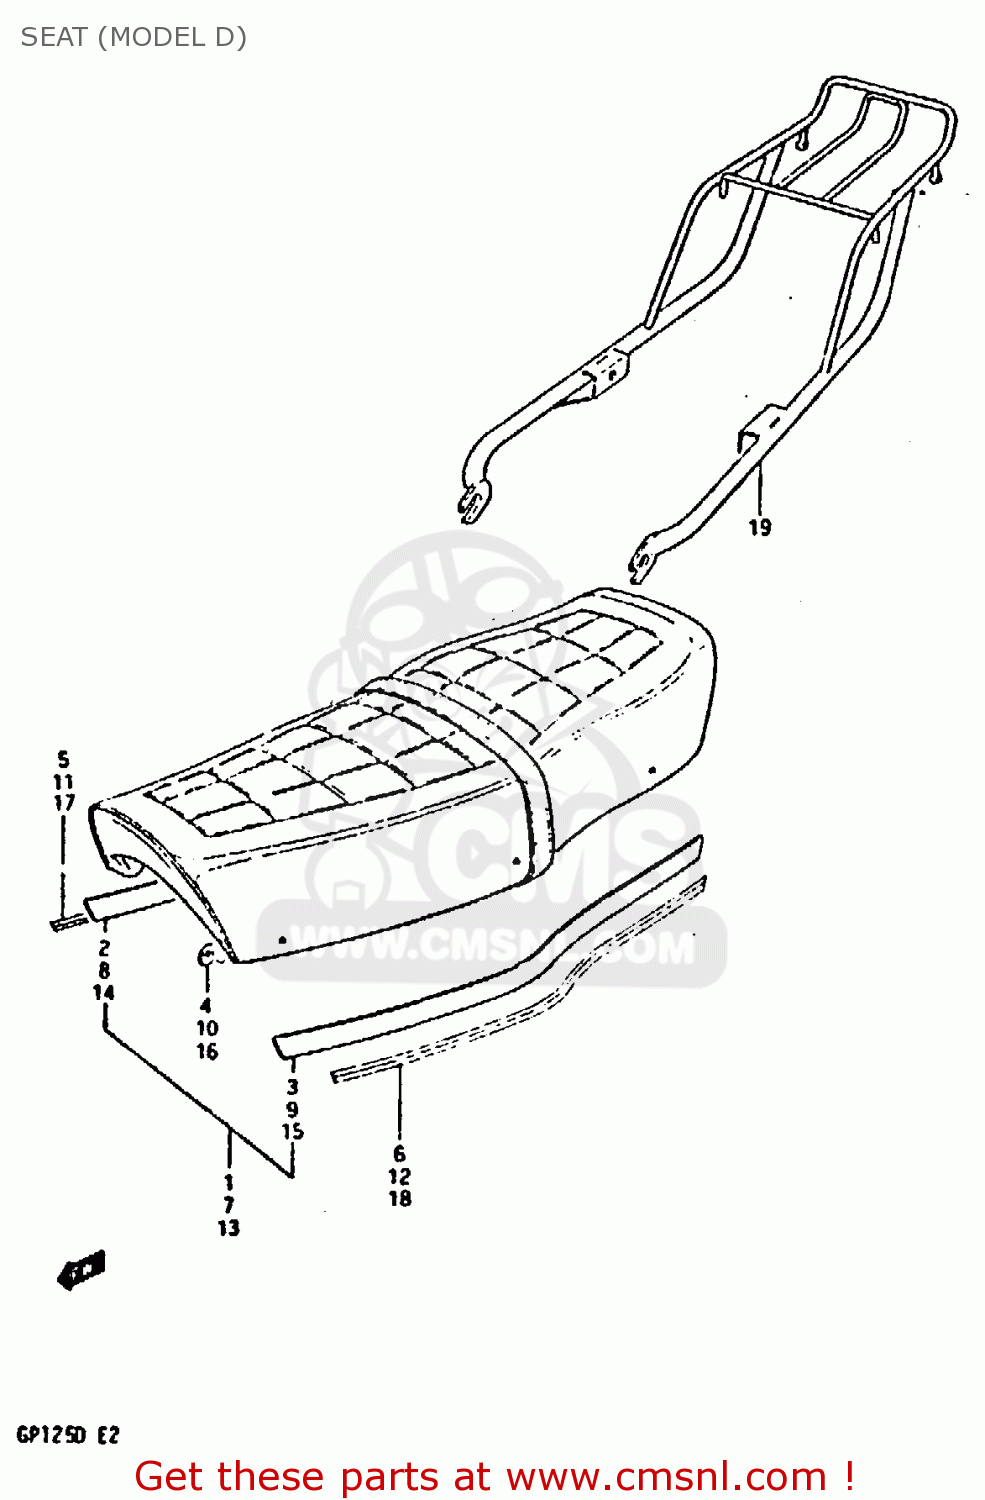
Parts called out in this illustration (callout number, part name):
1	SEAT ASSY
2	MOULDING, RH
3	MOULDING, LH
4	NUT
5	TAPE, MOLDING RH
6	TAPE, MOLDING LH
7	SEAT ASSY
8	MOULDING, RH
9	MOULDING, LH
10	NUT
11	TAPE, MOLDING RH
12	TAPE, MOLDING LH
13	SEAT ASSY
14	MOULDING, RH (BLACK)
15	MOULDING, LH (BLACK)
16	NUT
17	TAPE, MOLDING RH
18	TAPE, MOLDING LH
19	CARRIER,SPORT
